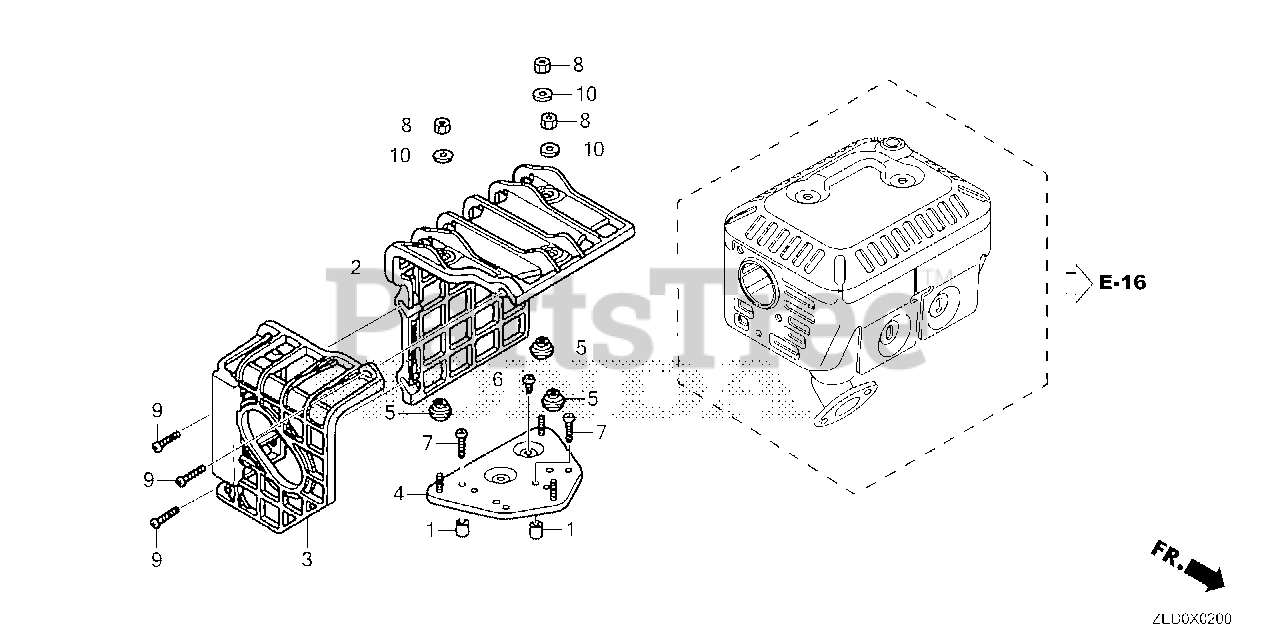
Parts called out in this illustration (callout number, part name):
1	COLLAR, AIR CLEANER HOUSING
2	COVER, MUFFLER
3	COVER, RR. MUFFLER
4	BASE, MUFFLER COVER
5	SPACER, MUFFLER COVER
6	SCREW, TAPPING (5X8)
7	SCREW, TAPPING (5X25)
8	NUT, HEX. (5MM)
9	SCREW-WASHER (6X20)
10	WASHER, PLAIN (5MM)
